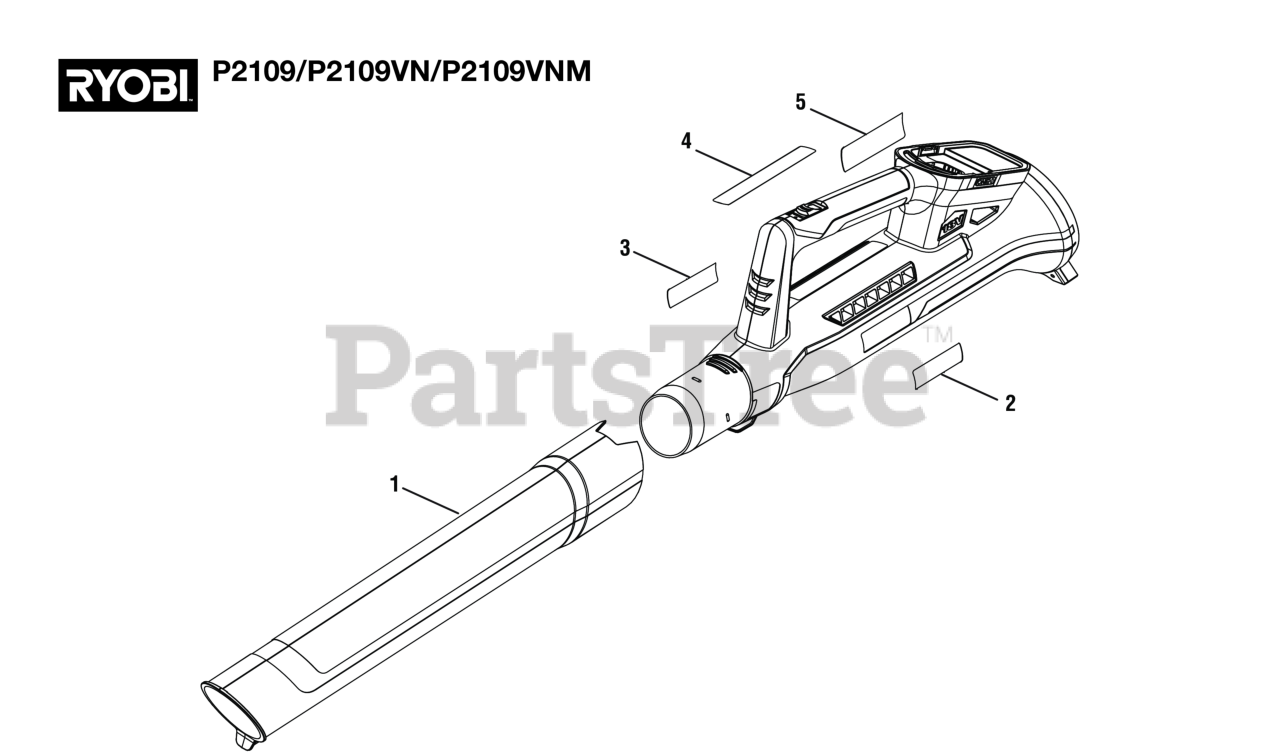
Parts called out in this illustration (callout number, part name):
1	Blower Tube
2	Logo Label
3	Data Label
4	Icon Label
5	Warning Label
